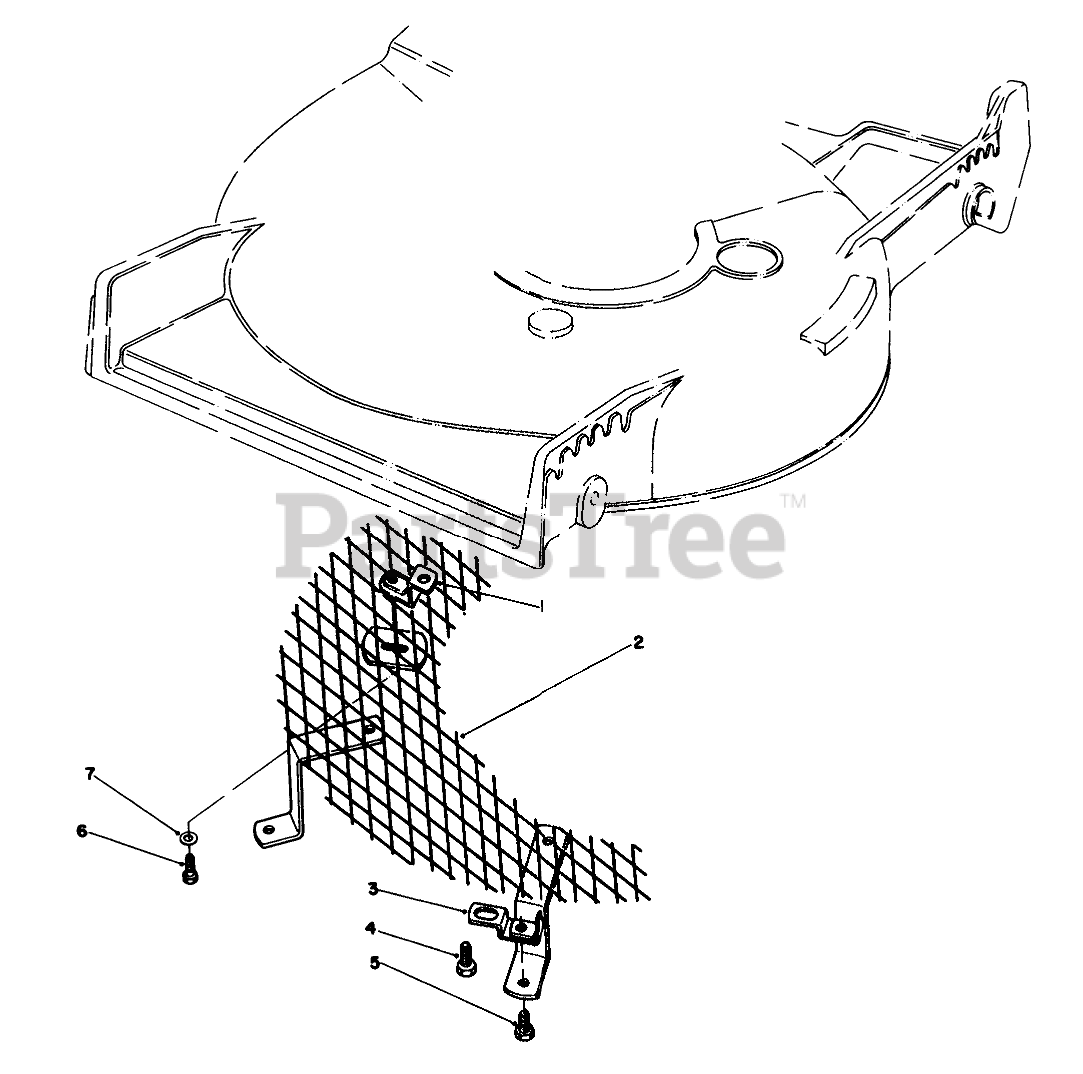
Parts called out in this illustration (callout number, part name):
1	BRACKET WA
2	SCREEN WA
3	Mounting Bracket
4	Screw-Self Tapping
5	SCREW-HH
6	SCREW-HH
7	WASHER-FLAT
